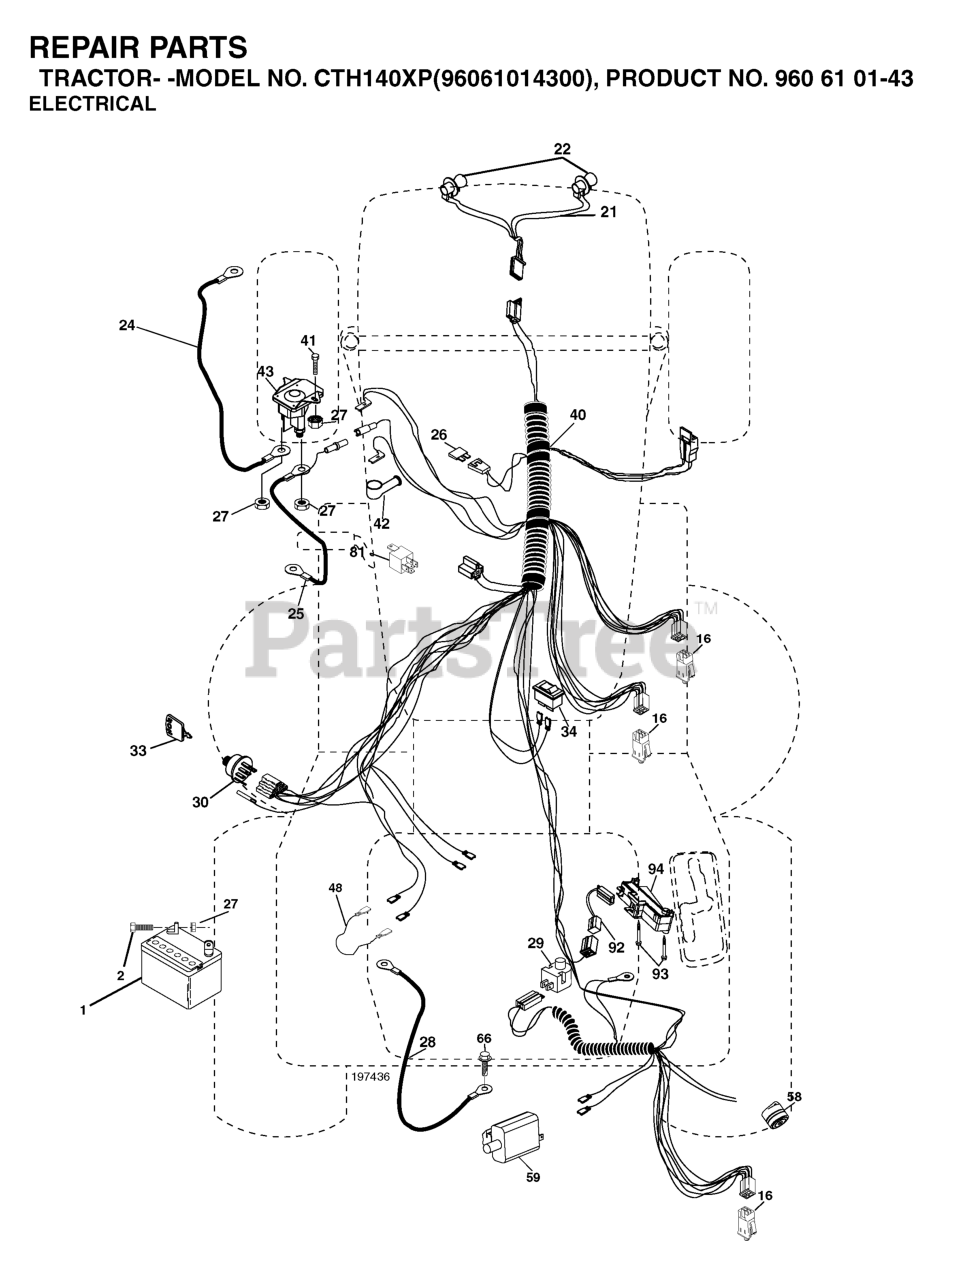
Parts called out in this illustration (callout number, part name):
1	BATTERY 12V .35 AMP
2	BOLT.HEX.1/4.X.3/4.DICHROMATE
16	SWITCH INTERLOOK PUSH-IN
21	HARNESS.W/LIGHT SOCKET
24	BATTERY CABLE GT
25	CABLE BATTERY
26	FUSE 20AMP
27	NUT
28	CABLE GROUND
29	SWITCH.SEAT.DP W/RAMPS
30	SWITCH.IGN.DELTA.W.LGH.ROS
33	KEY MLD GEN DELTA
41	BOLT
42	TERMINAL COVER
43	SOLENOID.W/BRASS.PLUNGER
48	ADAPTER.AMMETER
58	BUZZER
59	.WITCH.FULL BAGGER.INDICATOR
81	RELAY.ASSY.T
92	HARNESS.PIGTAIL.CONSLE
93	SCREW.PLASTITE
94	MODULE.REVERSE.ROS
